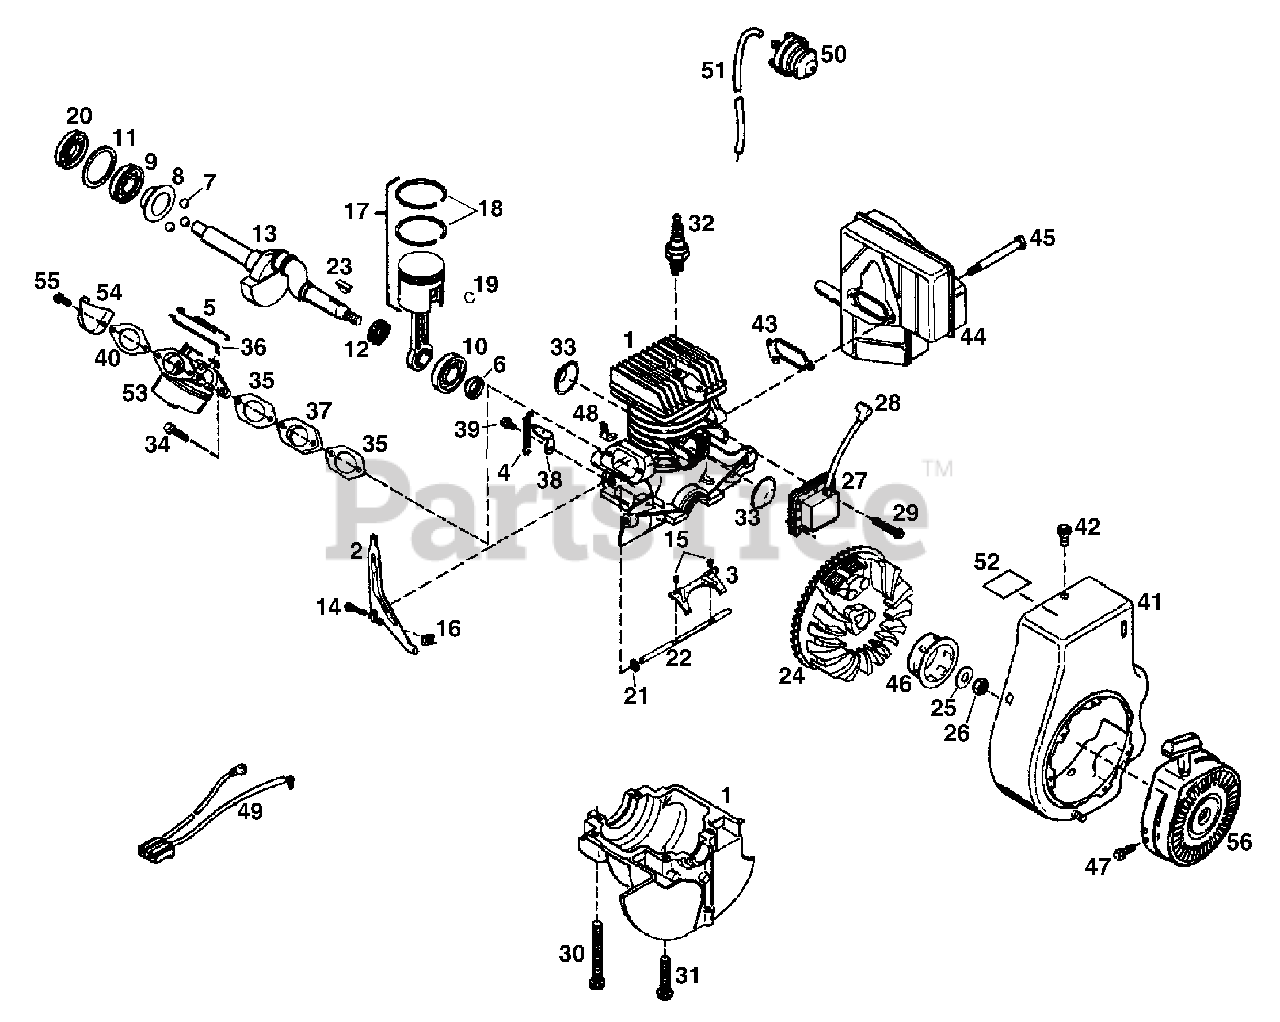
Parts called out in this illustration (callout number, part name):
1	Cylinder Ass’y
2	Governor Lever
3	Governor Lever
4	Extension Spring
5	Throttle Link Spring
7	Ball Bearing
8	Slide Ring
9	Ball Bearing
10	Ball Bearing
11	Bearing Retainer
12	Bearing Strip (31 Needles)
13	Crankshaft
14	Screw, 10-32 x 3/4"
15	Screw, 4-40 x 1/4"
16	Lock Nut, 10-32
17	Piston & Rod Ass’y
19	Piston Ring Retaining Ring
22	Governor Shaft
23	Flywheel Key
25	Bell Washer
26	Flywheel Nut
27	Solid State Ignition
28	Spark Plug Cover
29	Screw, Torx T-15, 10-24 x 15/16".
30	Screw, 5/16-18 x 2-3/16".
31	Screw, 5/16-18 x 1-5/8".
32	Resistor Spark Plug
33	Port Cover
34	Screw, 5/32 Allen, 1/4-20 x 5/8".
35	Carburetor Gasket
36	Governor Link
38	Control Lever
39	Screw, 8-32 x 1/2".
40	Air Cleaner Gasket
41	Blower Housing
42	Screw, 5/16-18 x 5/8".
43	Exhaust Gasket
45	Screw, 5/16-18 x 3-13/64".
46	Starter Cup
47	Screw, 8-20 x 21/64".
48	Wire Clip
49	Wire Harness
50	Primer Ass’y
51	Primer Line
52	Lubrication Decal
53	Carburetor
55	Screw, Torx T-25, 10-32 x 3/8".
56	Rewind Starter
